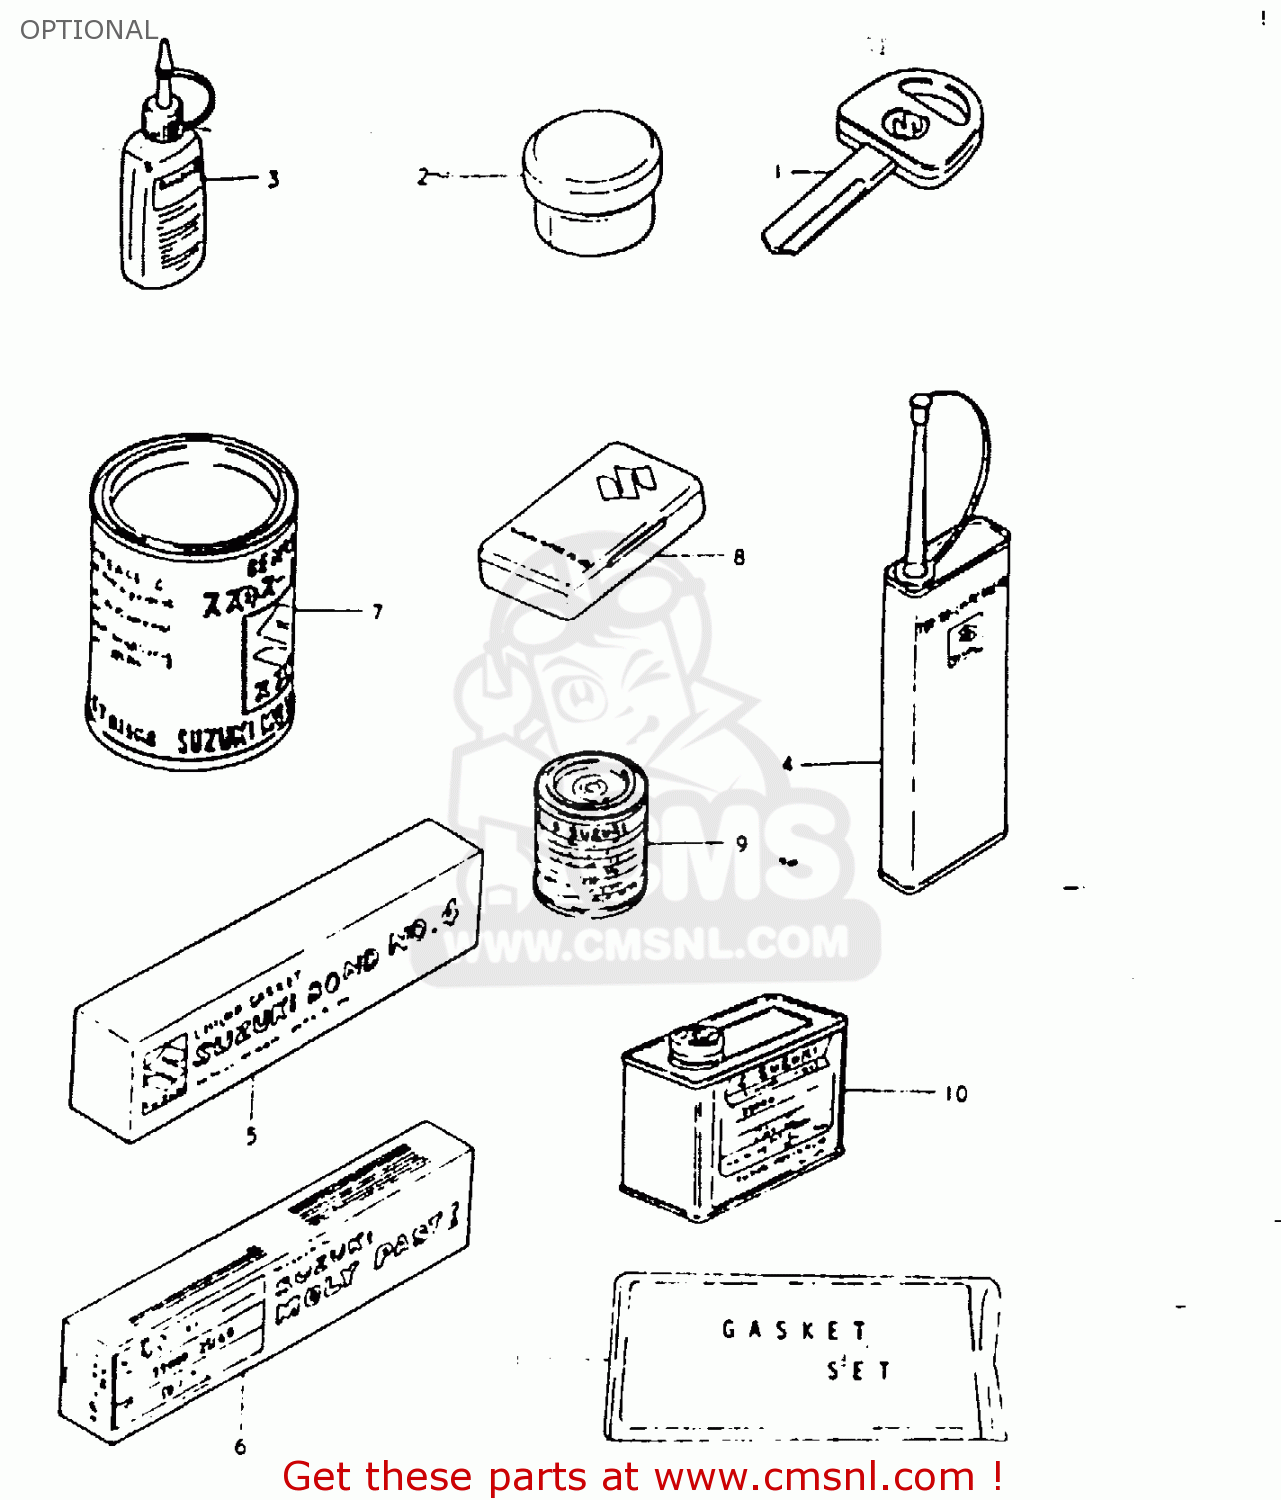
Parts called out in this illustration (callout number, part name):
1	KEY,BLANK
2	GREASE,PBC FOR BRK PAD 20G
3	THREAD LOCK SUPER (1332B)
4	THREAD LOCK NO.1401 CLEAR 200G
5	BOND 1104
6	SUZUKI MOLY PASTE
7	GREASE(C)EP2 LITHIUM 150G
8	TUBE REPARING TOOL
9	PAINT,BLACK
10	PAINT (BLACK)
11	GASKET SET
